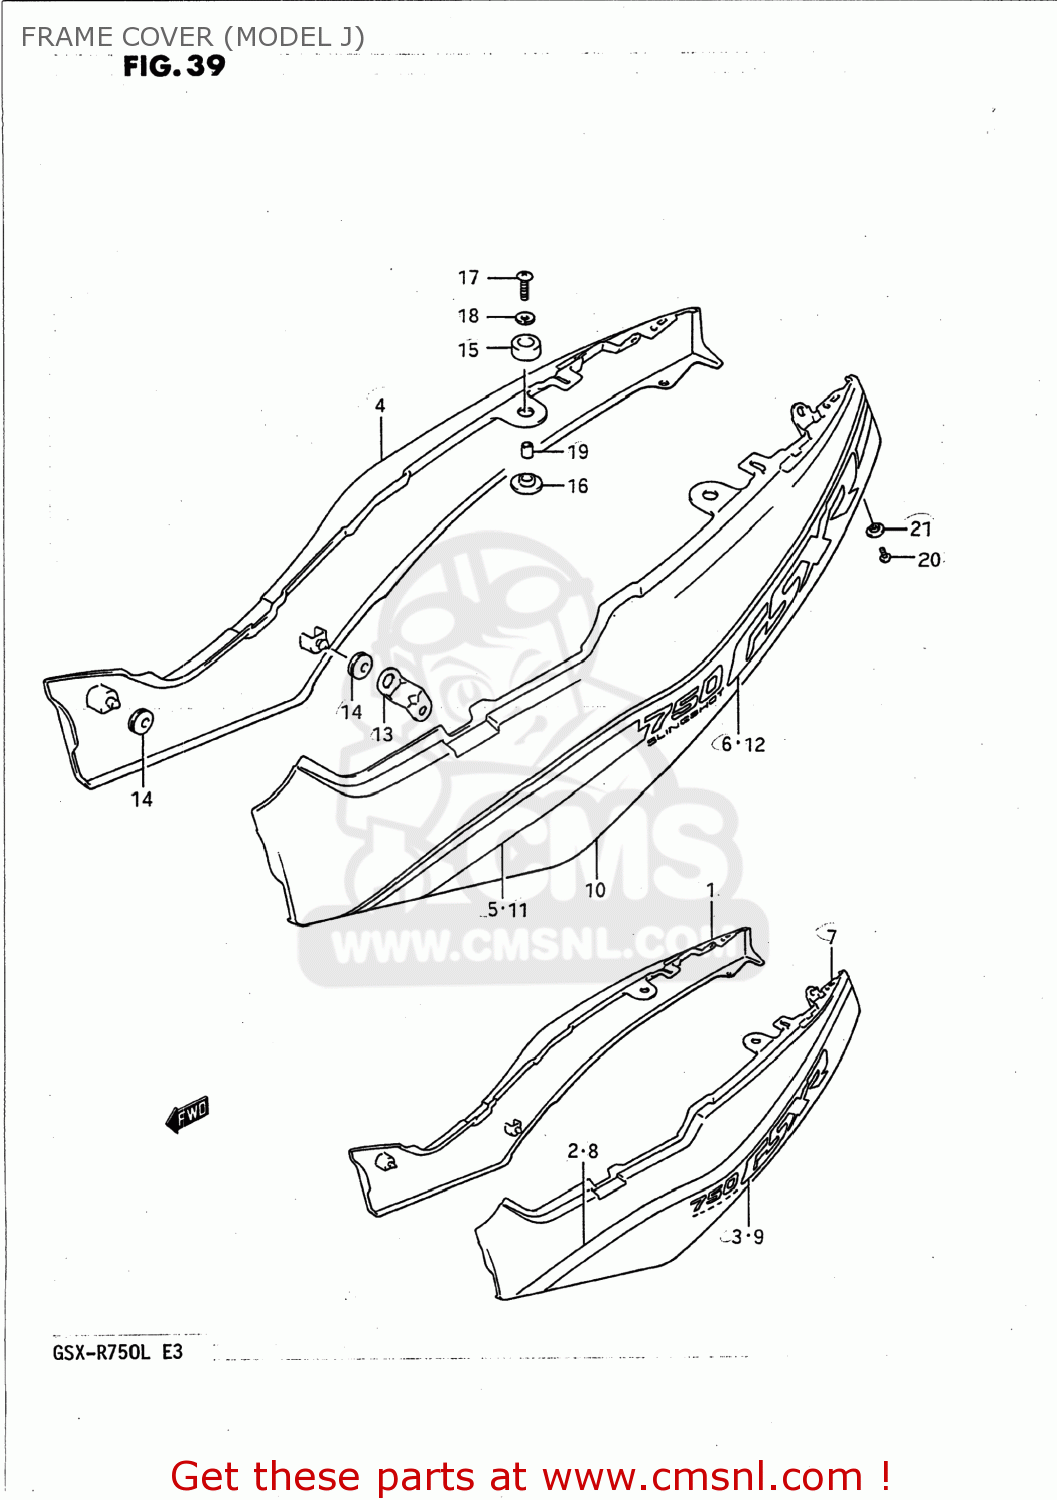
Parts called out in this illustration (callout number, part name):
1	COVER,FRAME,RIGHT
2	TAPE,FRAME COVER,RIGHT (WHITE)
3	EMBLEM,FRAME COVER,RIGHT
4	COVER COMP,FRAME,RIGHT
5	TAPE SET,FRAME COVER STRIPE
6	EMBLEM,FRAME COVER,RIGHT
7	COVER,FRAME,L
8	TAPE,FRAME COVER,LEFT (WHITE)
9	EMBLEM,FRAME COVER,L
10	COVER COMP,FRAME,LEFT
11	TAPE SET,FRAME COVER STRIPE
12	EMBLEM,FRAME COVER,LEFT
13	BRACKET,FRAME COVER
14	CUSHION
15	CUSHION,TAIL COVER UPR
16	CUSHION,FRAME COVER LWR
17	SCREW
18	WASHER
19	SPACER
20	SCREW
21	WASHER(5.2X14X1.5)
